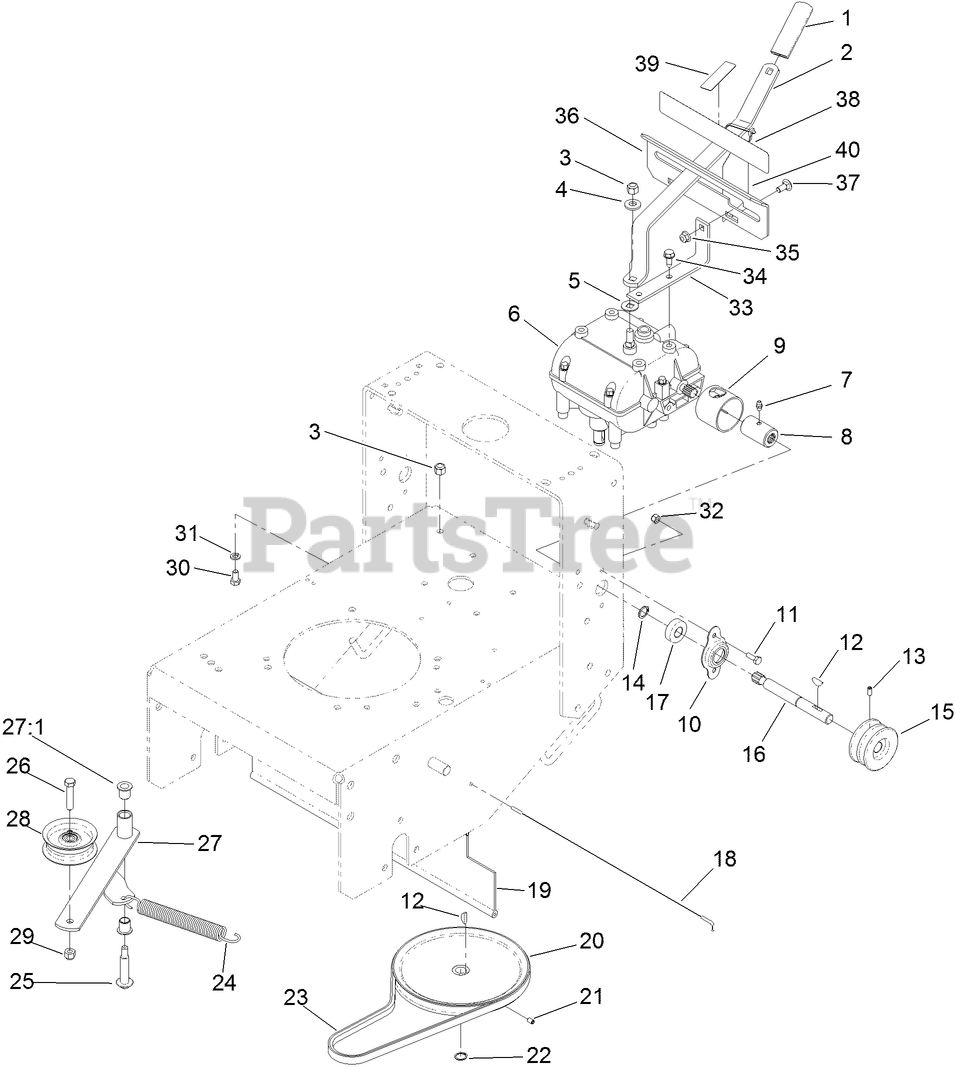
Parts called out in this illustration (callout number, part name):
2	LEVER-SHIFT
3	NUT-LOCK
4	WASHER-BELLEVILLE
5	WASHER
6	TRANSMISSION
7	FITTING-GREASE
8	COUPLER
9	GUARD-COUPLER
10	FLANGE-OUTPUT
11	SCREW-HH
12	KEY-WOODRUFF
13	SCREW-SET, HSH
14	RING-RETAINING
15	PULLEY-TRANSMISSION
16	SHAFT-OUTPUT
17	BEARING-SHAFT
18	ROD-SHIELD
19	SHIELD-TRAILING
20	PULLEY-DRIVEN
21	SCREW-HSH
22	RING-SNAP, EXTERNAL
23	V-BELT
24	SPRING-EXTENSION
25	BOLT-WHEEL
26	SCREW-HH
27	LEVER-IDLER
27:1	BUSHING-FLANGE
28	PULLEY
29	NUT-LOCK, NI
30	SCREW-HH
31	WASHER-LOCK
32	NUT-LOCK, NI
33	BRACKET-PLATE, SHIFT
34	SCREW-HWHTF
35	NUT-HF, NI
36	PLATE-SHIFT
37	BOLT-CARR
38	DECAL-SPEED, GROUND
39	DECAL-CAUTION, GEARBOX
40	HANG TAG-GEARBOX
